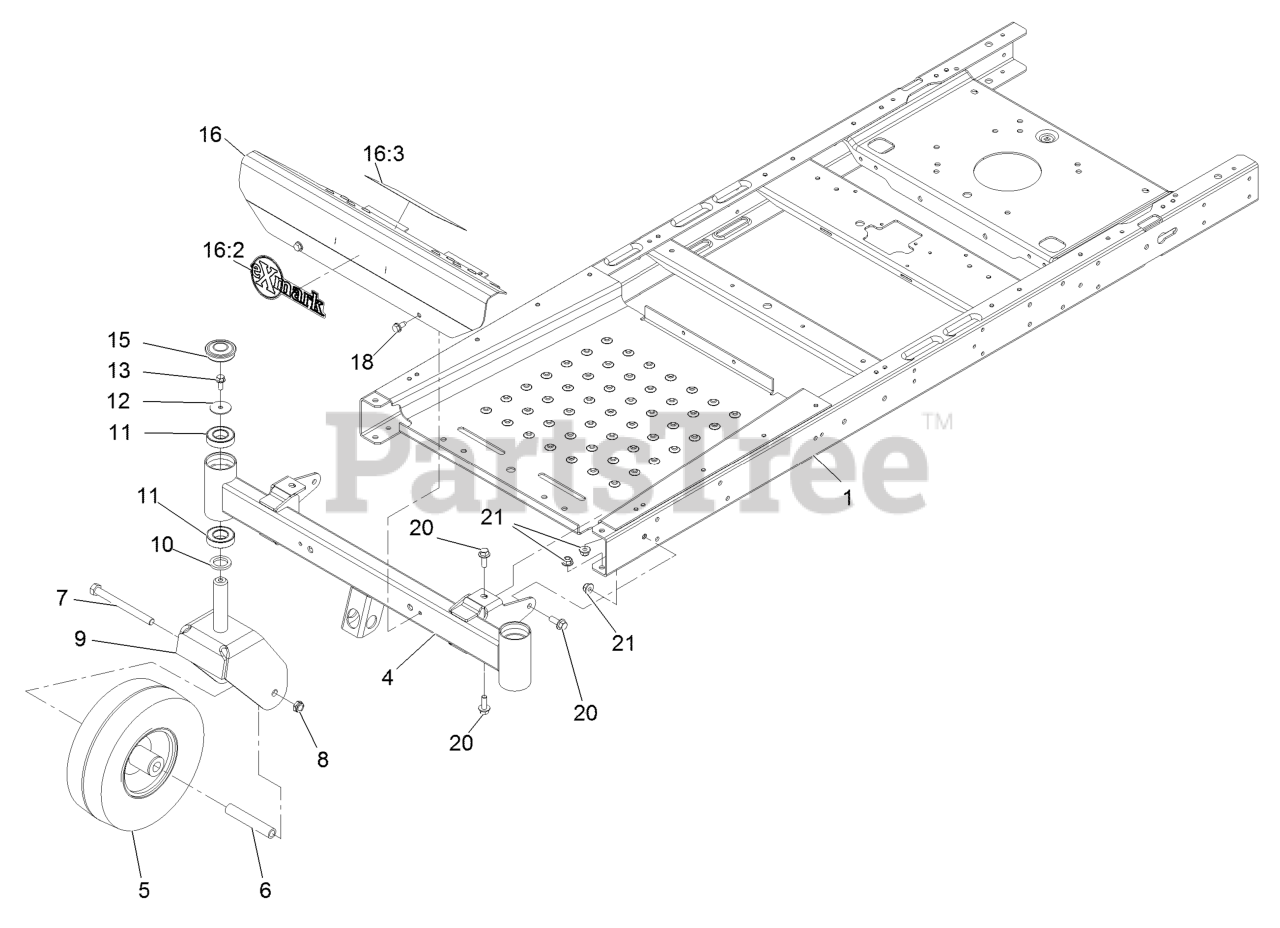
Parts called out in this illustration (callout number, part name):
1	FRAME ASM
5	13 INCH WHEEL AND TIRE AS
6	SPANNER
7	WASHER-LOCK
8	NUT-HEX
9	FORK-CASTER
10	WASHER-THRUST
11	BEARING-BALL
12	WASHER-FLAT
13	SCREW-HHF
15	CAP-GREASE
16	FOOTREST ASM
16:2	DECAL-EXMARK LOGO
16:3	DECAL-DANGER
18	Screw-HWH 5/16-18 X 3/4 Tf
20	SCREW-HHF 3/8-16 X 1
21	NUT-HF, NI
